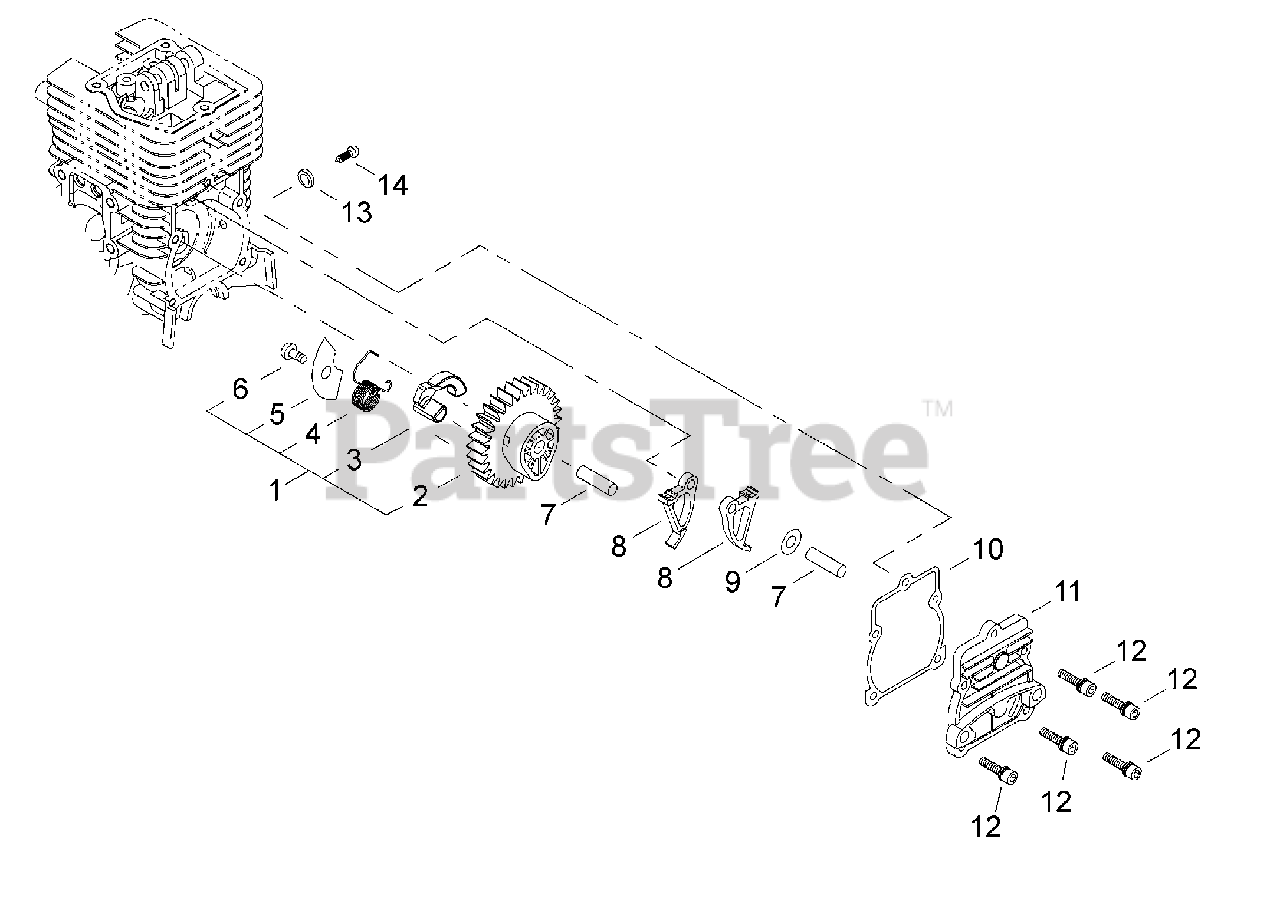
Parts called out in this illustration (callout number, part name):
1	CAM GEAR ASSY
2	GEAR, CAM
3	WEIGHT
4	SPRING
5	PLATE, COVER
6	SCREW, TAPPING 4×6
7	PIN, LOCATING Ø5×29.8 MM
8	FOLLOWER, CAM
9	WASHER 5 MM
10	GASKET, CAM GEAR
11	COVER, CAM GEAR
12	BOLT M4×14
13	WASHER Ø10ר5.5×2
14	SCREW M5
